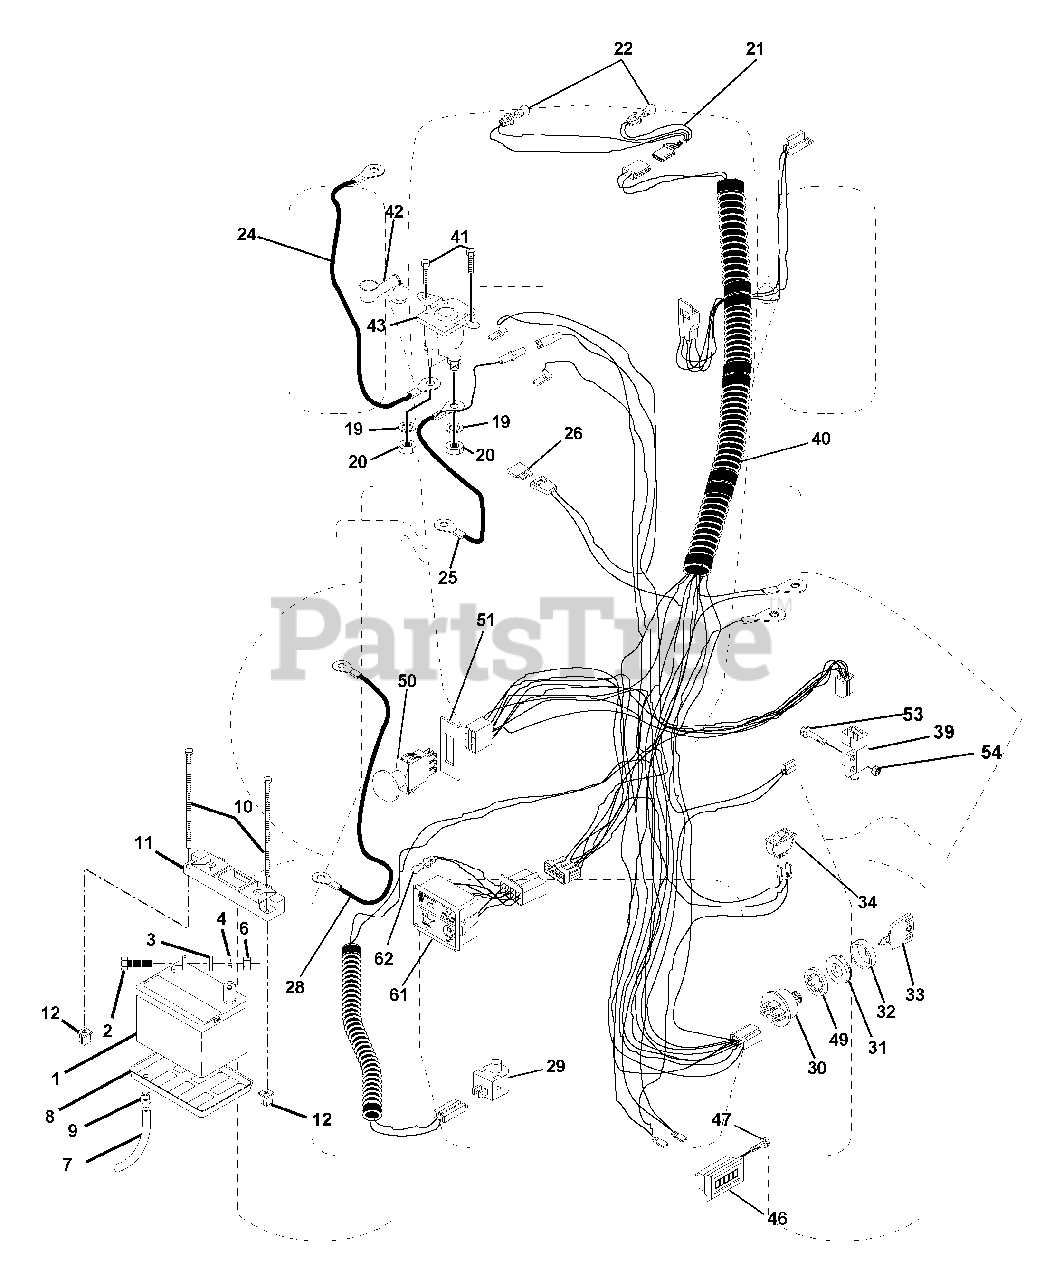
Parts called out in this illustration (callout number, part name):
1	Battery
2	Bolt Hex Head 1/4-20 x 3/4
3	Washer, Lock 1/4
4	Washer 9/32 x 5/8 x 16 Ga
6	Nut Fin Hex 1/4-20
7	Tube Plastic
8	Tray, Battery
9	Clamp, Hose
10	Bolt, Btr Frt 1/4-20 x 7-1/2 Zinc
11	Holddown Battery Dash Mount
12	Nut Push Nylon 1/4" Battery Frt.
19	Washer, Lock 1/4
20	Nut, Jam Hex 1/4-20
21	Harness Socket Light w/4152J
22	Bulb Light
24	Cable, Starter
25	Cable, Battery
28	Cable, Ground
29	Switch, Plunger
30	Switch, Ign
31	Nut, Ignition Switch
32	Cover Switch Key
34	Switch, Light
39	Intlk Switch
40	Harness Ign.
41	Screw 1/4-20 x 1/2
42	Cover, Terminal Red
43	Solenoid
46	Meter Hour
47	Screw #10-24 x 1/2
49	Washer, Lock Internal Tooth 5/8
50	Switch, PTO
51	Ring Retainer PTO
53	Screw Hex Washer Hd #10-32 x 1
54	Nut Keps #10-32
61	Light Pkg Asm
62	Bulb, Light Pkg.
